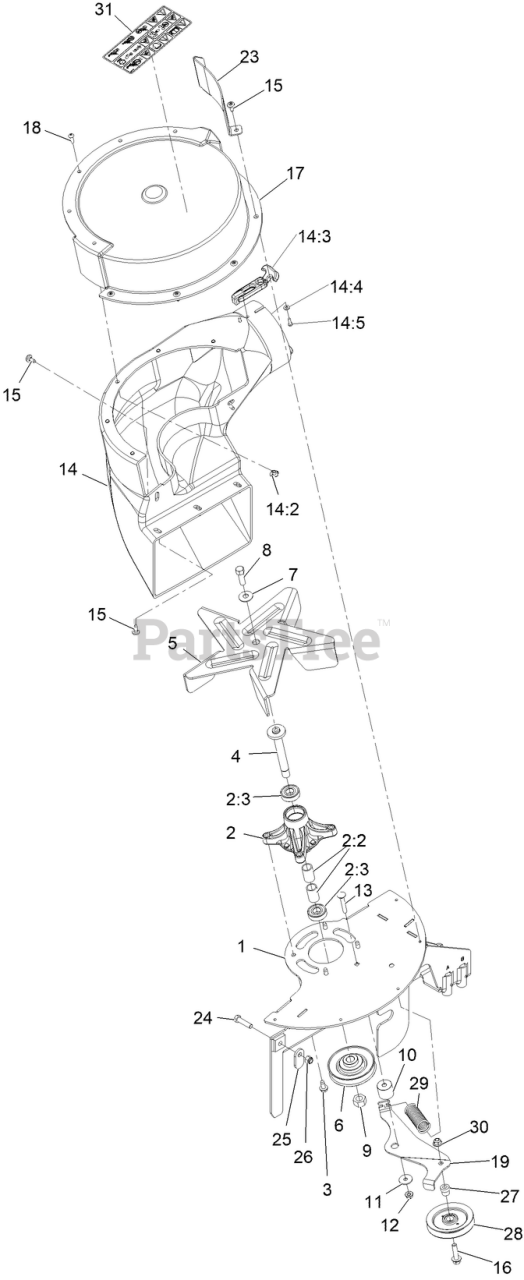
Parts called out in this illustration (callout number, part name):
1	WELD, BLOWER FRAME
2	SPINDLE ASM
2:3	BEARING-BALL
3	Screw-HWH 5/16-18 X 3/4 Tf
4	Shaft - Spindle
5	Fan-Blower
6	SHEAVE-BLOWER OFFSET
7	WASHER-BELLEVILLE
8	Screw-HH
9	Nut-Hex
10	SPACER-STEPPED
11	WASHER-PIVOT
12	NUT-HF, NI
13	SCREW-CARR
14	ASM-Blower Chute, Plastic
14:2	Insert-T-Nut
14:3	LATCH-RUBBER
14:4	WASHER-FLAT
14:5	SCREW-PPH
15	SCREW-SHOULDER
16	SCREW-HHF
17	ASM-BLOWER COVER
18	SCREW-PRH
19	ARM-IDLER, BLOWER
23	Guard-Blower
24	SCREW-HH
25	LATCH-CATCHER, GRASS
26	NUT-LOCK, NI
27	HUB,SPACER
29	SPRING-IDLER
30	NUT-HF, NI
31	DECAL-WARNING BLOWER W/RO
